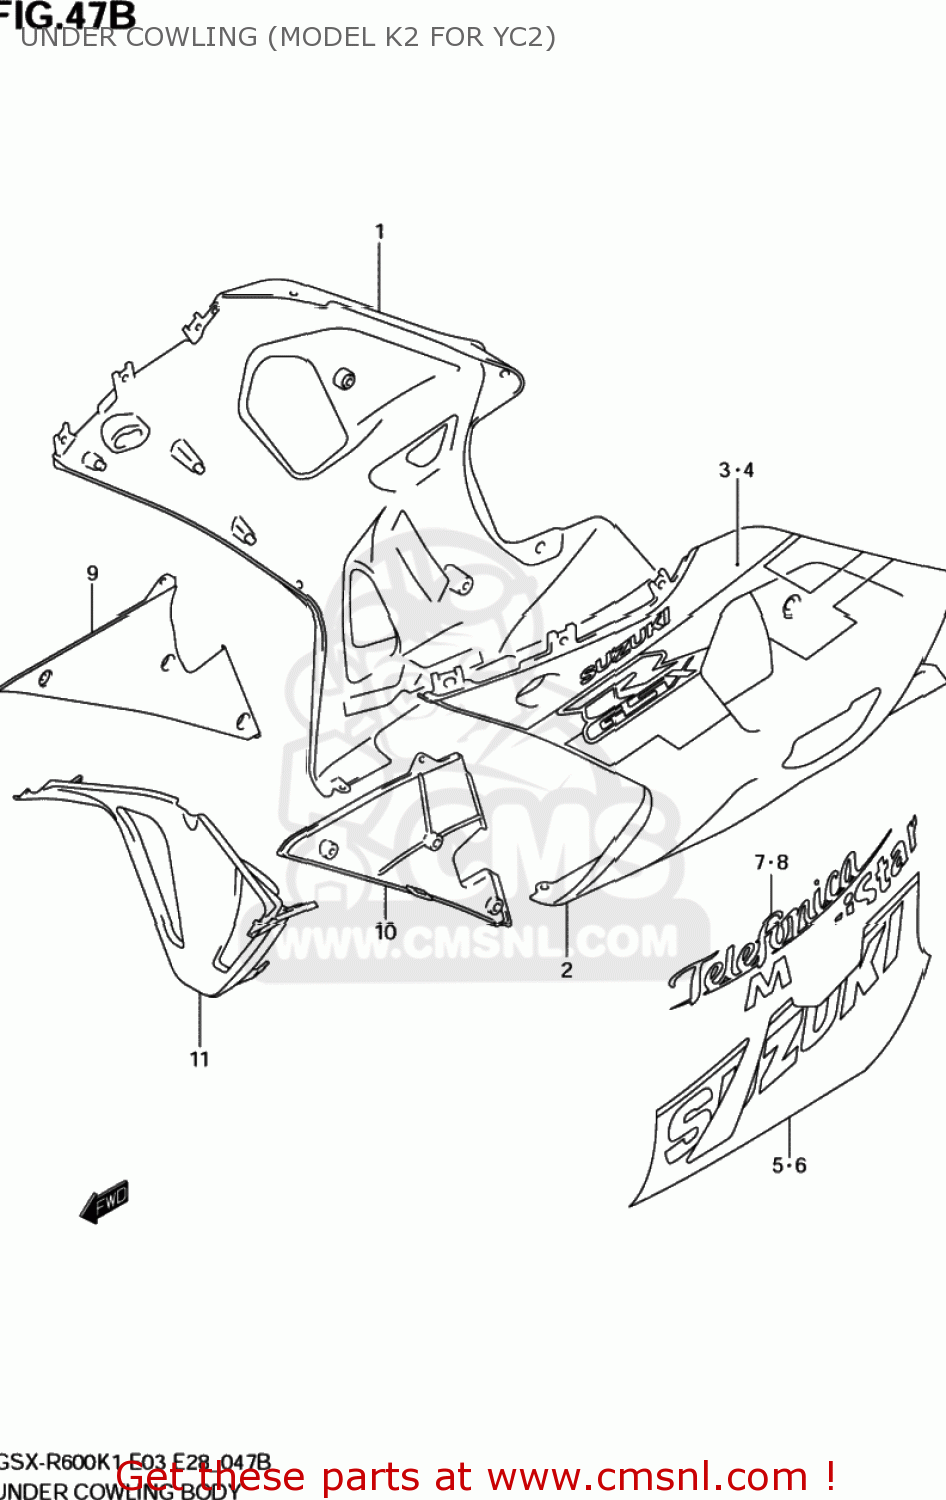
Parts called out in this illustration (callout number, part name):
1	COWLING ASSY,UNDER,R
2	COWLING ASSY,UNDER,L
3	TAPE SET,UPPER
4	TAPE SET UPPER
5	TAPE,LWR,R
6	TAPE,LWR,L
7	EMBLEM SET,UNDER,R
8	EMBLEM SET,UNDER,L
9	COWLING,UNDER INNER,R
10	COWLING,UNDER INNER,L
11	COWLING,UNDER CTR
